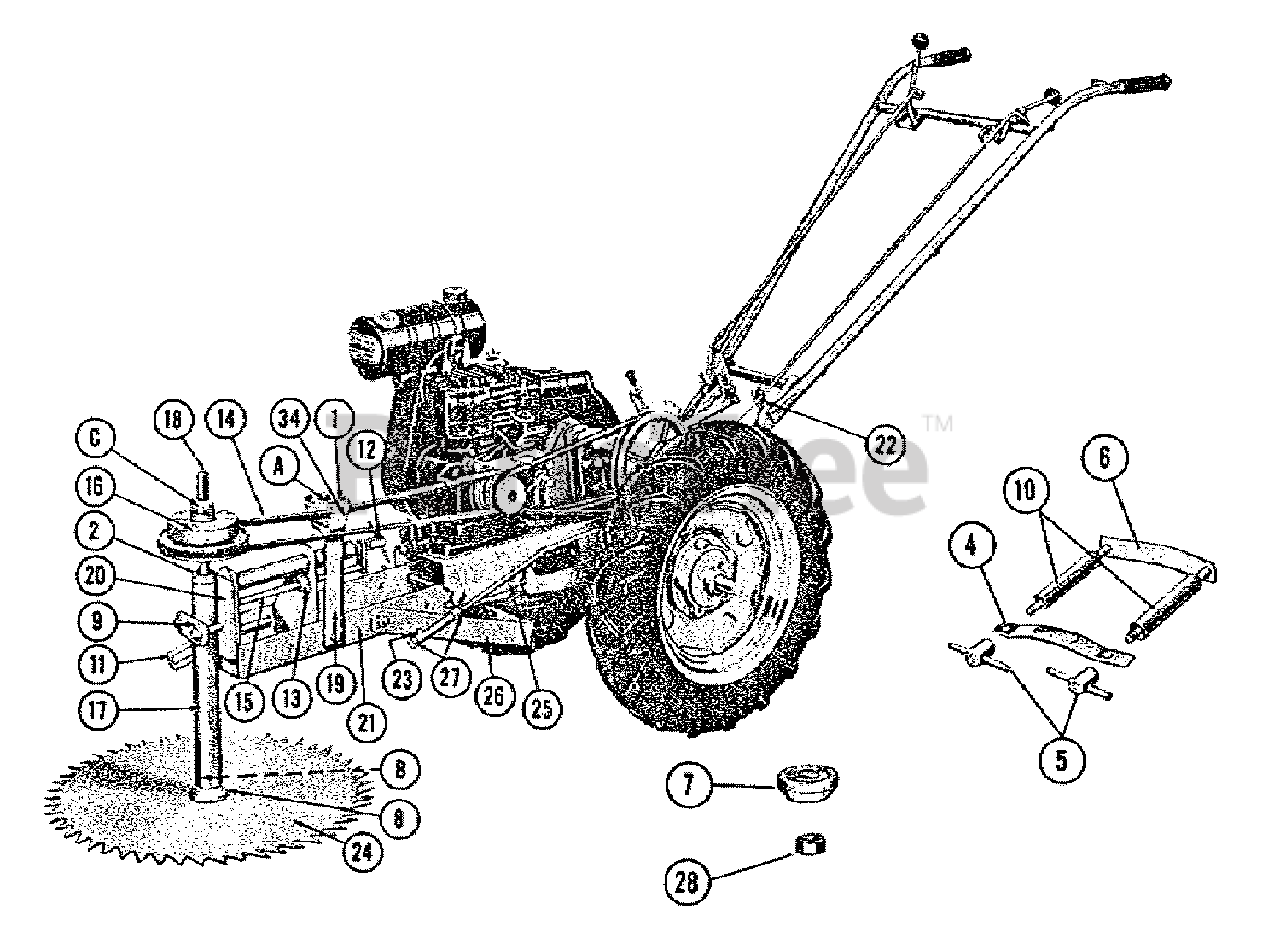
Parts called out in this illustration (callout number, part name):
1	IDLER PULLEY
2	SET COLLAR (Arbor Shaft)
4	HITCH SIDE PLATE
5	T-NUT, Complete
6	HITCH CLAMP ASSEMBLY
7	LOWER FLANGE
8	UPPER FLANGE
11	ARBOR PROP
12	TIGHTENER SCREW
13	SET COLLAR (Tightener Assembly)
14	A-56 SUPER COMBINE V BELT 58 "
15	TIGHTENER ASSEMBLY
16	CLUTCH ASSEMBLY
17	BEARING HOUSING WITH BUSHINGS
19	IDLER BRACKET
20	ARBOR HOLDER ASSEMBLY
21	FRAME ASSEMBLY
22	SPRING CLIIP
23	ROD SOCKET ASSEMBLY
24	20" CORDWOOD SAW BLADE (1 3/8" Bore)
25	STAND ROD
27	SET COLLAR (Stand Rod)
28	NUT, Hex, Full, L.H.
29	BELT SUPPORT
A	INNER BEARING RACE
B	BUSHING FOR BEARING HOUSING
C	PULLEY KEY
